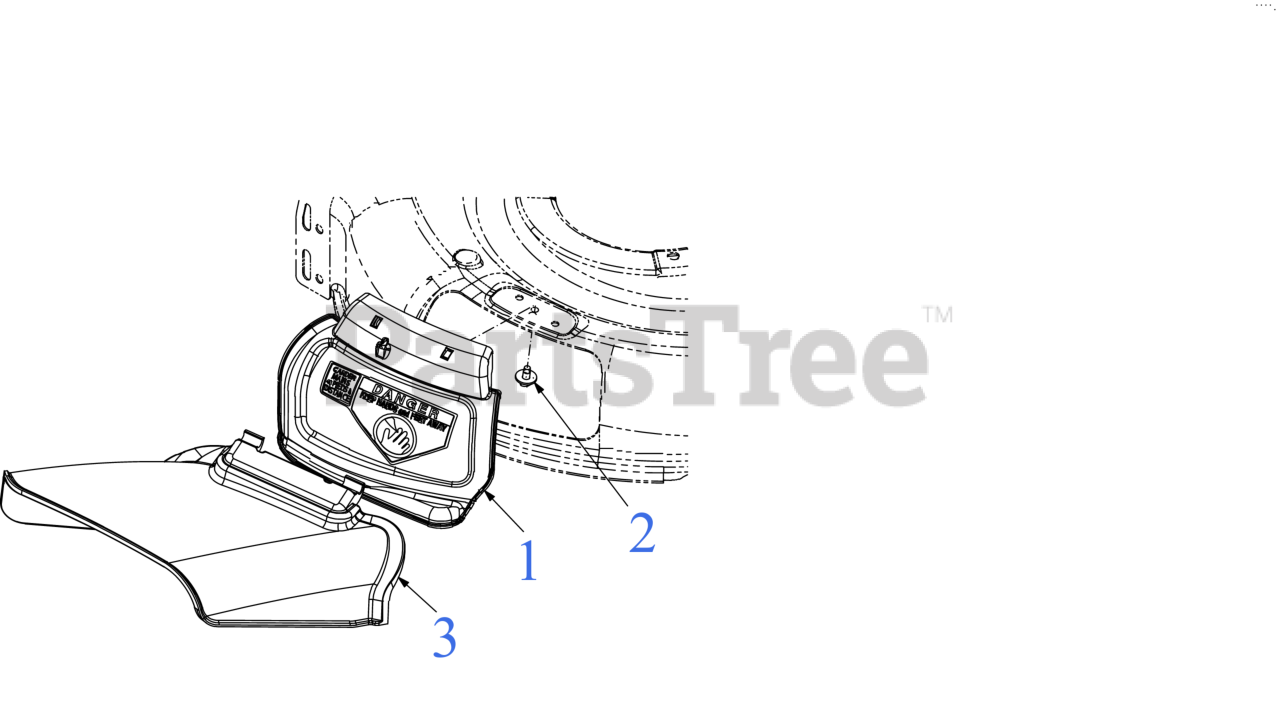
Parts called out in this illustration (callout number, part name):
1	21" MULCH PLUG (HINGED)
2	SCREW 1/4-20 x .50
3	SIDE DISCHARGE CHUTE
